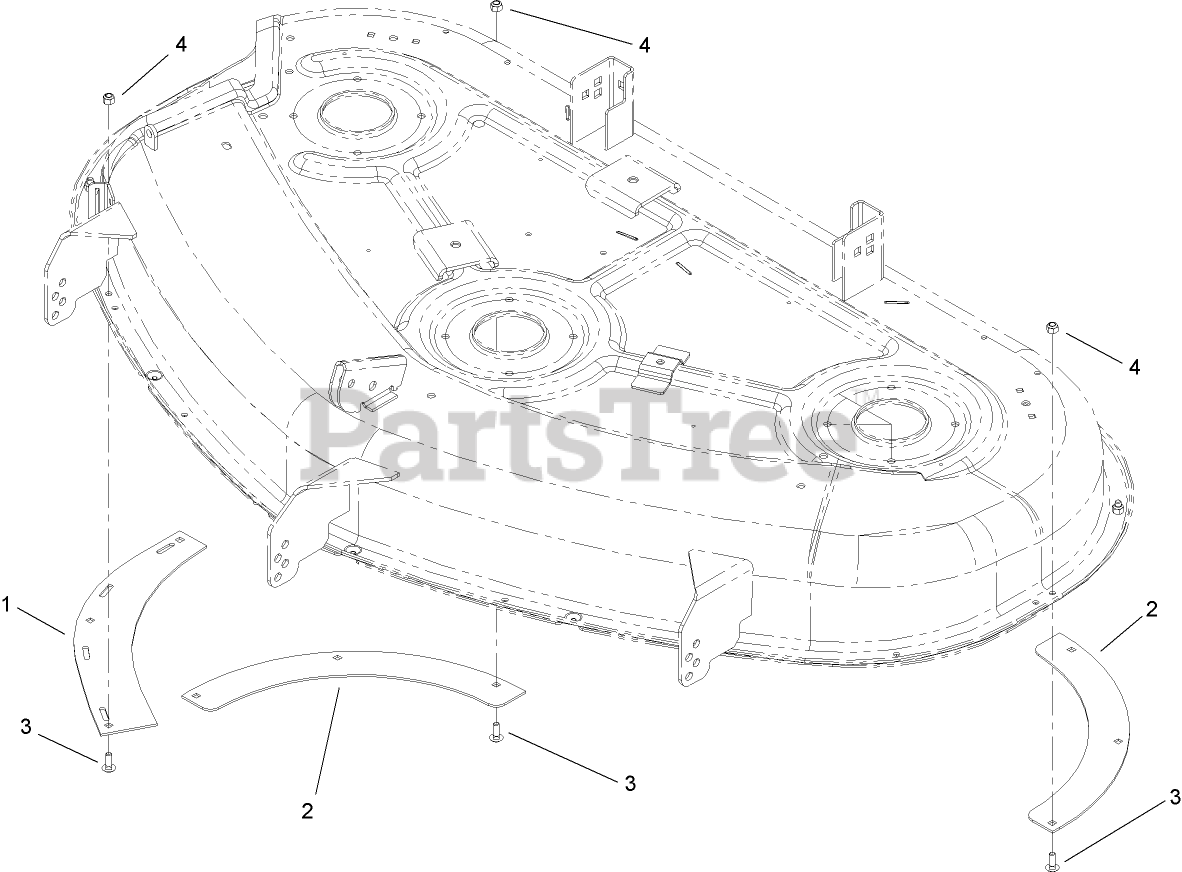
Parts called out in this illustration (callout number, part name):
1	BAFFLE-END
2	BAFFLE-REAR
3	BOLT-CARR
4	NUT-LOCK, NI
